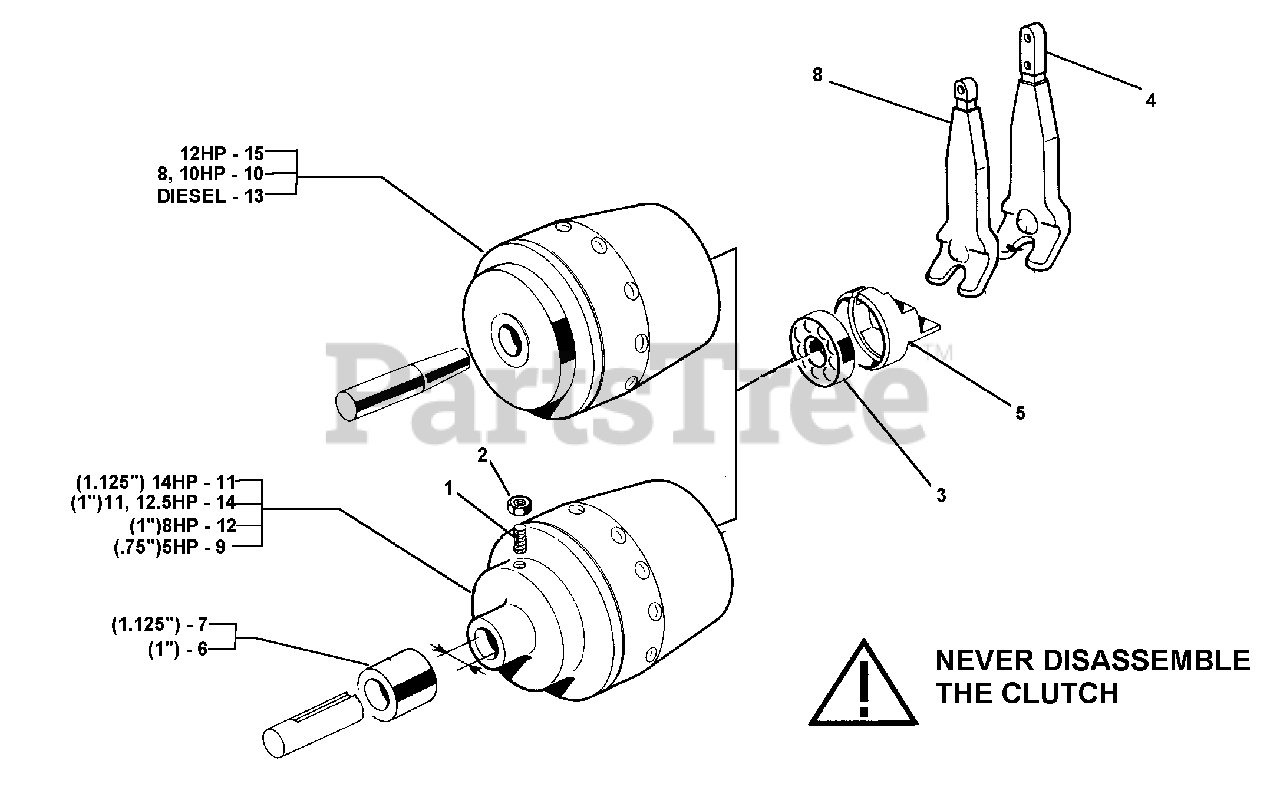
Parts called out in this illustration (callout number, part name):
1	SET SCREW M8 X 30
3	BEARING 17 X 40 X 12
4	CLUTCH LEVER - RECOIL START
5	CONE PUSHER
6	SPACER 12.5HP VANGARD
8	CLUTCH LEVER - ELECTRIC START
9	HEAVY DUTY CLUTCH
10	HEAVY DUTY CLUTCH
11	HEAVY DUTY CLUTCH
12	HEAVY DUTY CLUTCH
13	HEAVY DUTY CLUTCH
14	HEAVY DUTY CLUTCH
15	HEAVY DUTY CLUTCH
